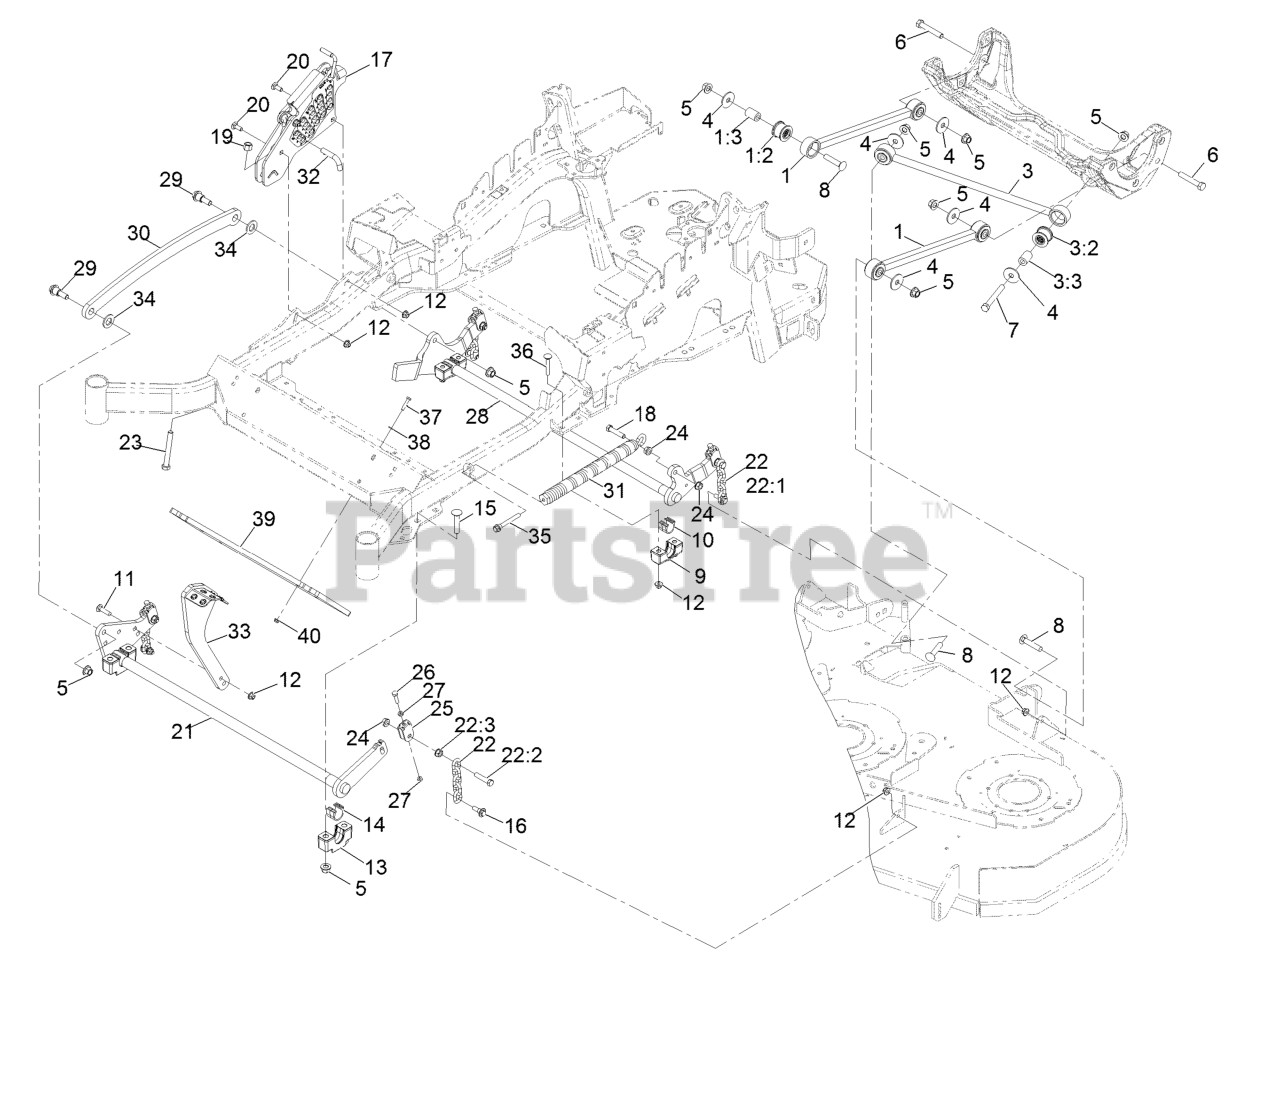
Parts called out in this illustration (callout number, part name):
1	Long Strut ASM
1:2	Bushing-Suspension, Rubber
3	Panhard Rod ASM
3:2	Bushing-Suspension, Rubber
5	Nut-Lock 1/2-13
6	Screw-HH 1/2-13 X 3
7	Screw-HH 1/2-13 X 4
8	Bolt-Carriage 1/2-13 X 2 1/2
9	Support-Cross Shaft, Bearing Rear
10	Bearing-Cross Shaft, Rear
11	Bolt-Carriage 3/8-16 X 1 1/2
12	Nut-Nyloc 3/8-16 Flg
13	Support-Cross Shaft, Bearing
14	Bearing-Cross Shaft, Front
15	Bolt-Carriage 1/2-13 X 2 1/2 Spl Neck
16	Screw-Hex Flange 3/8-16 X .80
17	HOC ASM
18	Screw-HH 7/16-14 X 2
19	Nut-Nyloc 1/2-13
20	Bolt-Carriage 3/8-16 X 1
21	Decklift-Front
22	Deck Lift Chain ASM
22:1	Chain-Lift, Deck
22:2	Screw-HH 7/16-14 X 2
22:3	Nut-Whizlock 7/16-14
23	Bolt-HH 1/2-13 X 4 Tap
24	Nut-Whizlock 7/16-14
25	Yoke-Adjust, Deck
26	Screw-HH 5/16-18 X 1 1/4
27	Nut-Jam 5/16-18
28	Lift-Deck, Rear
29	Screw-Shoulder HHF 1/2-13 X 1.12
30	Link-Lift, Deck
31	Spring-Extension
32	Pin-HOC
33	Lever-Foot
34	Washer-3/4 SAE
35	Screw-Shcs 3/8-16 X 2.212
36	Bolt-Carriage 3/8-16 X 2 1/4
37	Screw-HH 1/4-20 X 1 1/4
38	Washer-1/4 SAE
39	Weight-Toe Board
40	Nut-Nyloc 1/4-20 Flg
